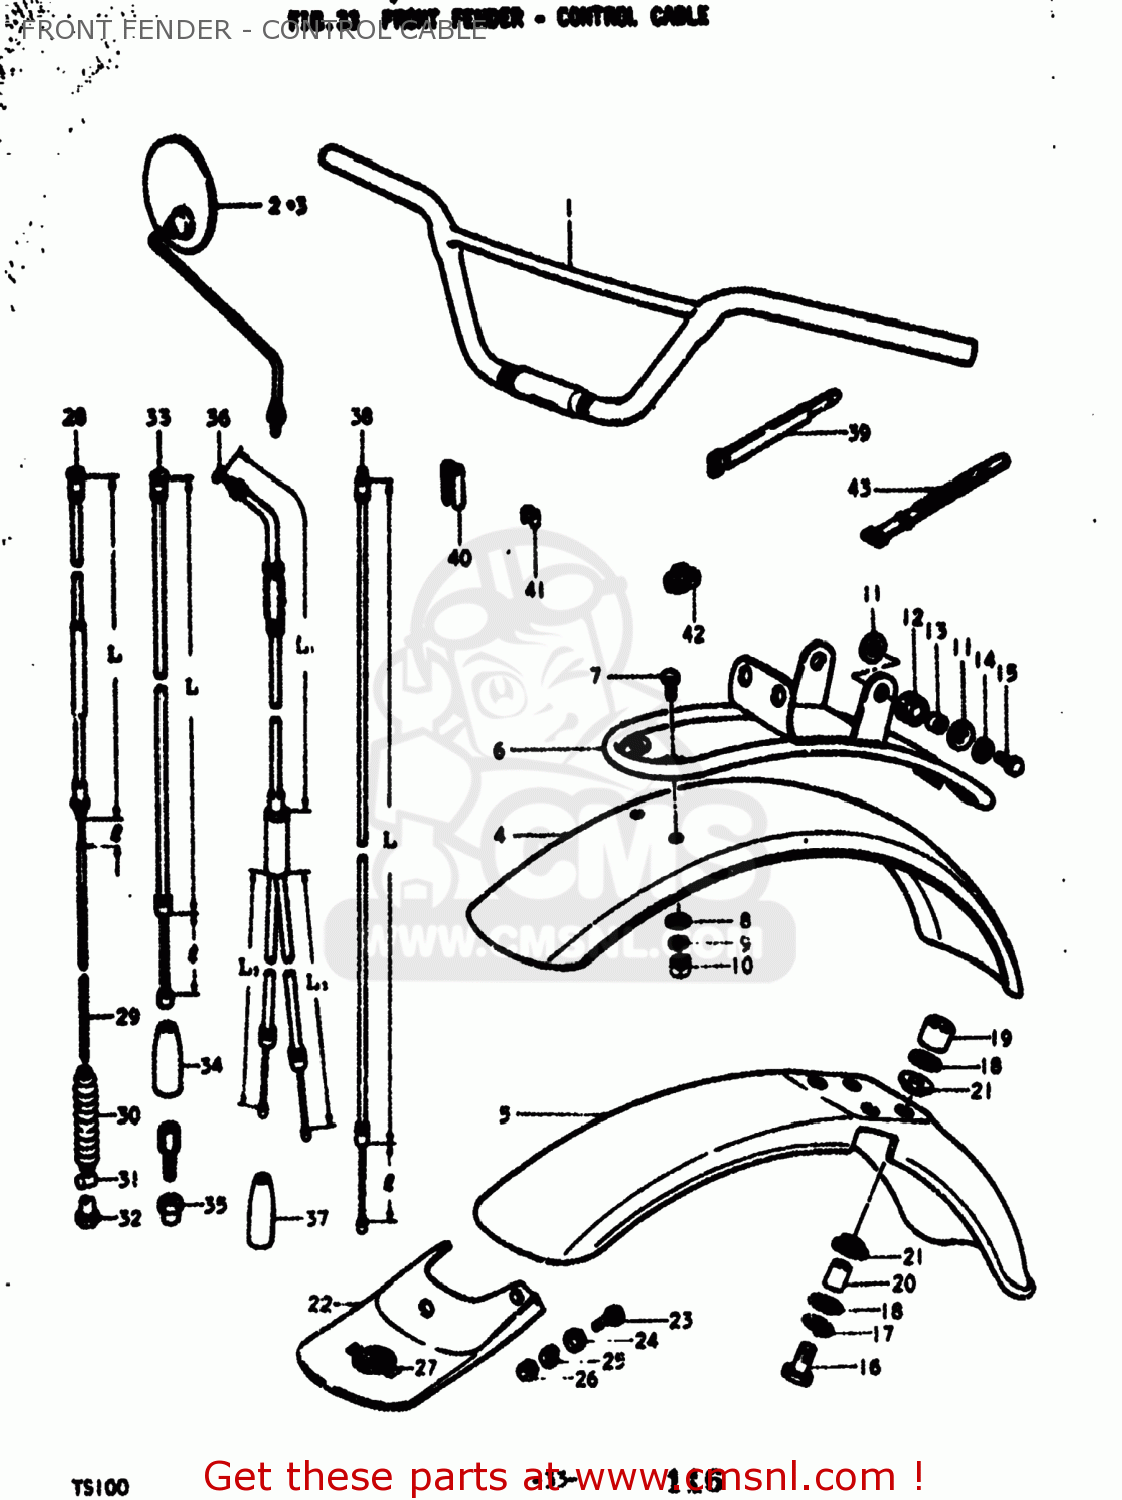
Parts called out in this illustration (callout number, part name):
1	HANDLEBAR
2	MIRROR ASSEMBLY,RIGHT
3	MIRROR ASSEMBLY,LEFT
4	FENDER,FRONT
5	FENDER,FRONT
6	BRACE,FRONT FENDER
7	BOLT
8	WASHER
9	LOCK WASHER
10	NUT
11	WASHER (6.5X20X1.2)
12	CUSHION
13	SPACER (7X9X7)
14	LOCK WASHER
15	BOLT(6X18)
16	BOLT
17	LOCK WASHER
18	WASHER (6.5X24X1.2)
19	SPACER (8X12X15)
20	SPACER (6.1X8X15.5)
21	CUSHION
22	MUD FLAP,FRONT FENDER
23	SCREW
24	WASHER
25	LOCK WASHER
26	NUT
28	CABLE ASSEMBLY,FRONT BRAKE
29	SPRING
30	SEAL,DUST(7X16X75)
31	PIN,10X19
32	NUT
33	CABLE ASSY,CLUTCH
34	SEAL,DUST(7X18X30)
35	NUT
36	CABLE ASSEMBLY,THROTTLE
37	SEAL,DUST(7X18X30)
38	CABLE COMP,STARTER
39	CLAMP
40	CLIP
41	CLIP
42	CLIP
43	CLAMP
